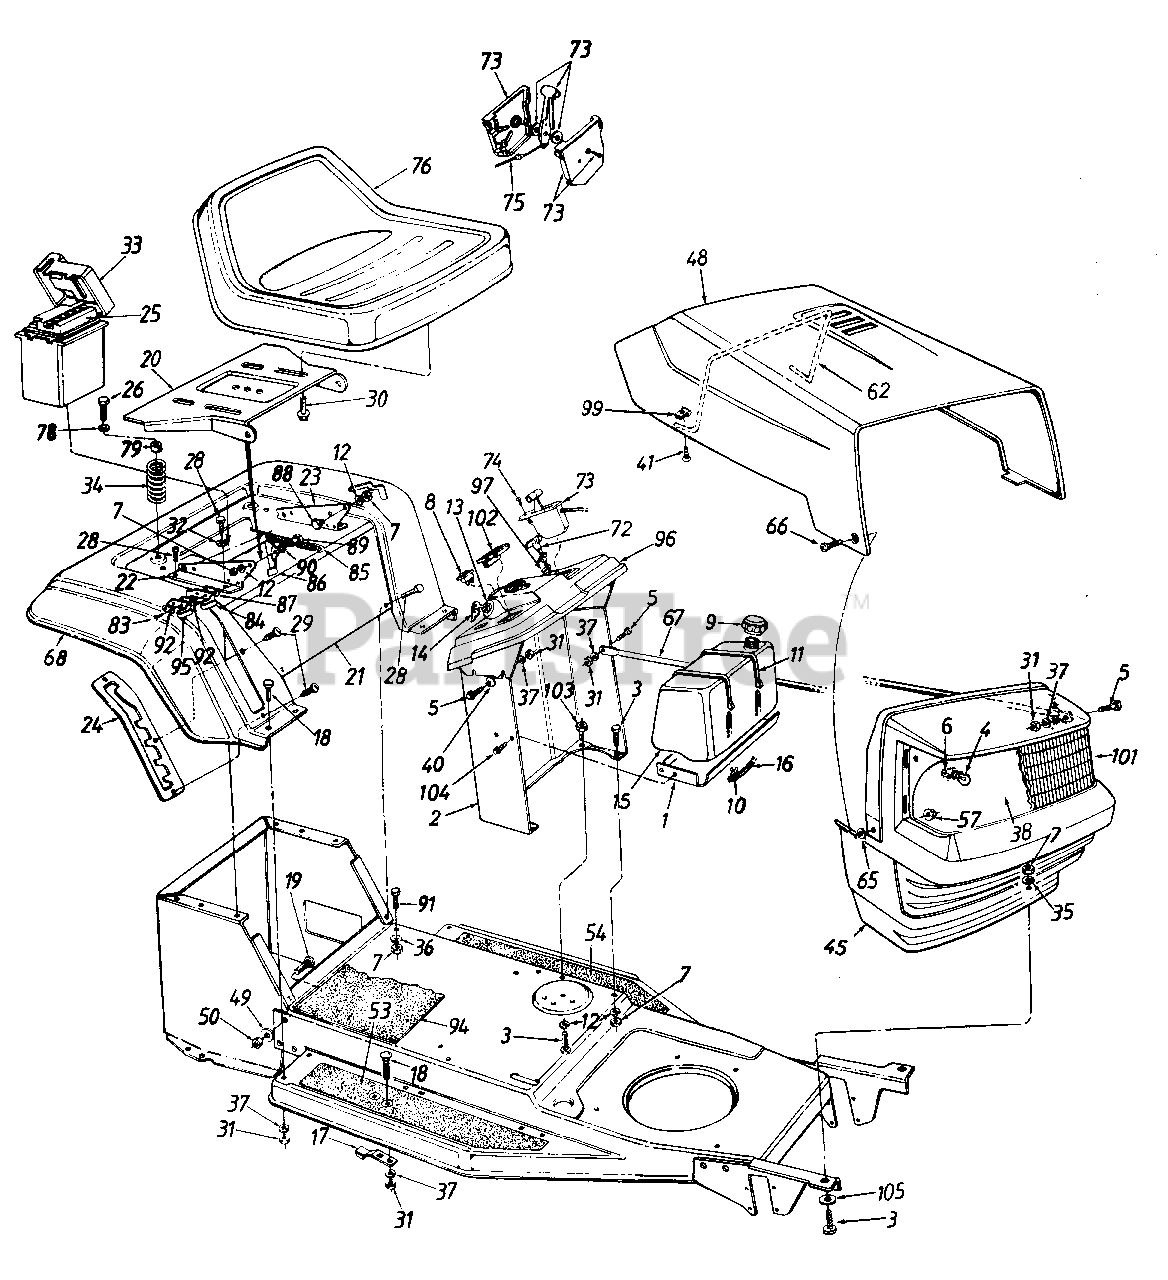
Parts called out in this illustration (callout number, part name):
4	Bulb
5	Truss Mach. Scr. 1/4-20 x .75" Lg.
6	Socket
7	Hex Nut 5/16-18 Thd.
8	Light Switch
9	Gas Cap
10	Hose Clamp
11	Cable Tie
12	L-Wash. 5/16" I.D.
13	Ignition Switch
14	Ignition Key
15	Fuel Tank
16	Gas Line 15" Long
17	Blade Brake Ass'y.
18	Carriage Bolt 1/4-20 x .62"
19	Ribbed Neck Bolt 3/8-24 x .8"
25	Battery
26	Hex Self-Tap Scr. 5/16-18 x 1.25" Lg.
28	Hex AB-Tap Scr. 5/16 x .75" Lg.
29	Torx Mach. AB-Tap Scr. 1/4 x .62" Lg.
30	Hex Self-Tap Scr. 3/8-16 x .75" Lg.
31	Hex Nut 1/4-20 Thd.
32	External L-Wash. 5/16" I.D.
33	Battery Box w/Cover
34	Compression Spring
35	Fl-Wash. .34" I.D. x 1" O.D.
36	Bell-Wash. 5/16" I.D.
37	L-Wash. 1/4" I.D.
38	Grille Reflector Label
40	Bell-Wash. .265" I.D. x .75"
41	Pan Hd. Scr. 10-24 x .75" Lg.
45	Grille
50	Hex L-Nut 3/8-24 Thd.
53	Foot Pad - R.H.
54	Foot Pad - L.H.
57	Lock Nut 1/4-28 Thd.
62	Hood Spring
65	Fl-Wash. .28" I.D. x .75" O.D.
66	Shld. Bolt
72	Choke Control
73	Throttle Control Box
74	Truss AB-Tap Scr. #10 x .5"
75	Throttle Wire (B&S)
76	Seat Assembly (Low Back)
78	Fl-Wash. .344" I.D. x .88" O.D.
79	Bushing
83	Hex Tap Scr. #8 x .5" Lg.
84	Safety Switch (Seat)
85	Ext. Spring 5.31" Lg.
86	Seat Lift Brkt.
87	Insulator Boss Plate
88	Shld. Bolt .437" Dia. x .162" Lg.
89	Shld. Bolt .437" Dia. x .268" Lg.
90	Spr. Wash. .445" I.D. x .75" O.D.
91	Hex Wash. Hd. Scr. 5/16-18 x .62" Lg.
92	Insulator Plate
94	Center Foot Pad
95	Safety Switch (Seat)
96	Dash Panel
97	Retainer Clip
99	Speed Nut
101	Lens
102	Ammeter
103	Hex Jam Nut 5/16-18 Thd.
104	Hex Wash. Hd. Tap Scr. 1/4-20 x .5" Lg.
